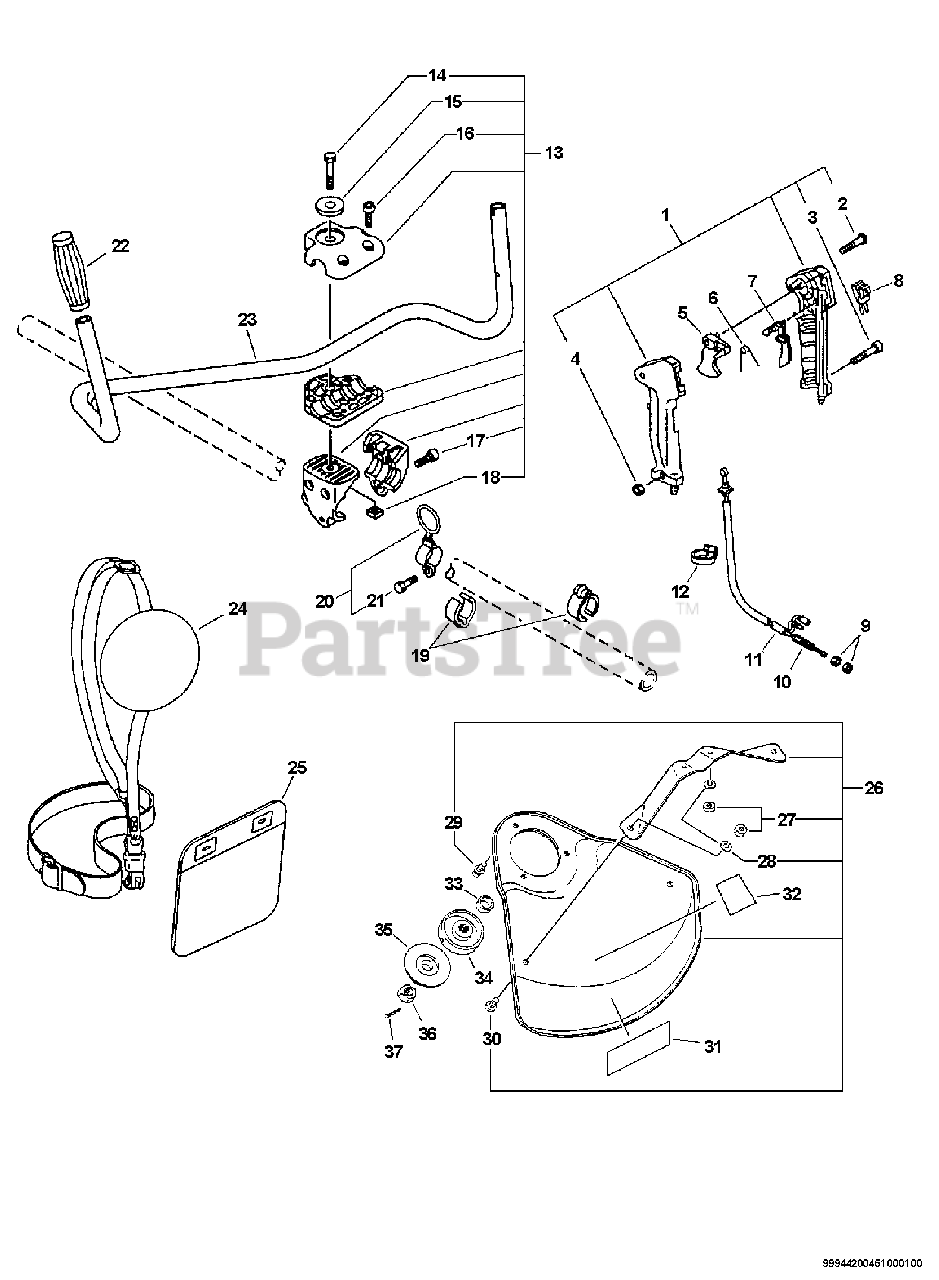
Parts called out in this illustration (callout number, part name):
1	THROTTLE CONTROL ASSY
2	SCREW - 3X25
3	SCREW - 5X30
5	TRIGGER, THROTTLE
6	SPRING, LOCKOUT LEVER
7	LOCKOUT, THROTTLE
8	IGNITION SWITCH ASSY
10	CABLE, THROTTLE
11	TUBE, PROTECTIVE - CORRUGATED
13	HANDLE BRACKET KIT
14	BOLT - 8X55
15	WASHER - 8
16	SCREW - 5X20
17	SCREW - 5X30
20	HANGER KIT
21	BOLT - 5X12
22	GRIP, HANDLE - LEFT
23	HANDLE - FRONT
24	SHOULDER STRAP ASSY
25	CUSHION
26	DEBRIS SHIELD KIT - METAL
28	LOCKWASHER - 5
29	SCREW - 5X10
30	SCREW - 5X8
31	LABEL - ECHO
32	LABEL - DANGER
34	ADAPTOR, BLADE - UPPER
35	ADAPTOR, BLADE - LOWER
36	NUT - 10 -- LEFT HAND
37	PIN, SPLIT - 2X22
